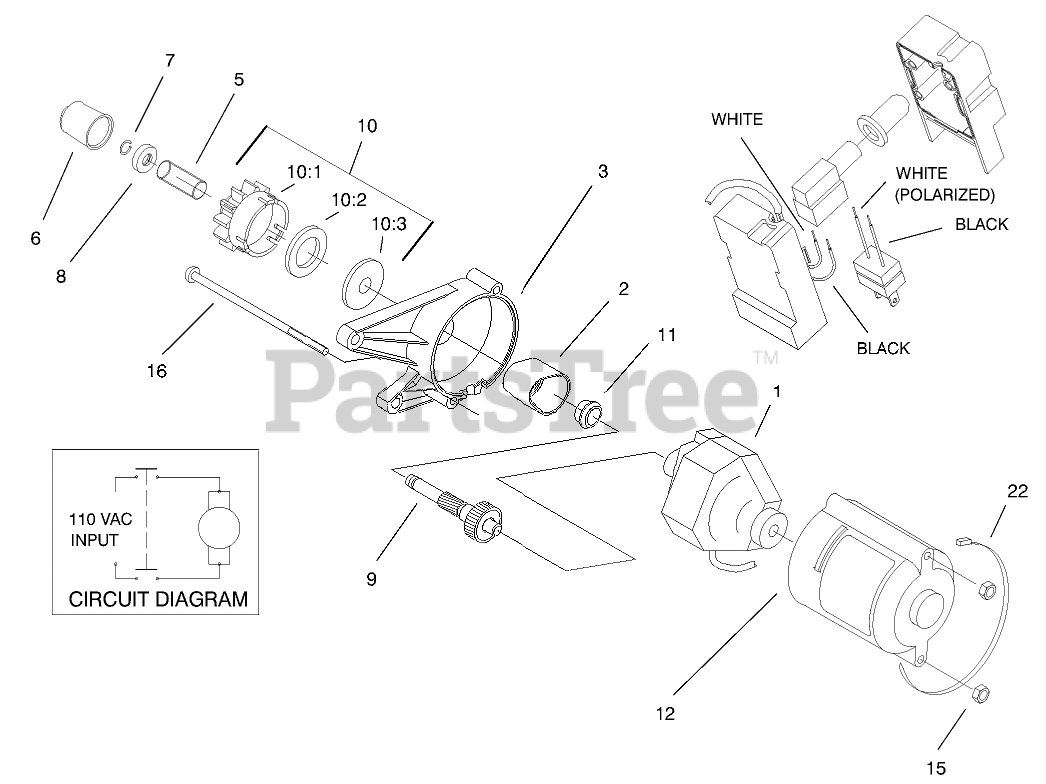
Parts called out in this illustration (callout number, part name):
1	Starter Motor Assembly (only on: 38182)
2	Cover-Gear (only on: 38182)
3	Housing-Upper Starter (only on: 38182)
5	Spring (only on: 38182)
6	Pinion-Cap (only on: 38182)
7	Ring-Lock (only on: 38182)
8	Stop-Pinion (only on: 38182)
9	Shaft/Gear ASM-Service (only on: 38182)
10	Pinion ASM (R & S)(only on: 38182)
10:1	Nut (only on: 38182)
10:2	Pinion (only on: 38182)
10:3	Ring-Rubber (only on: 38182)
11	Bushing (only on: 38182)
12	Housing-Lower Starter (only on: 38182)
15	Nut-Lock Ni (only on: 38182)
16	Screw-Mach (only on: 38182)
22	Tie-Cable (only on: 38182)
